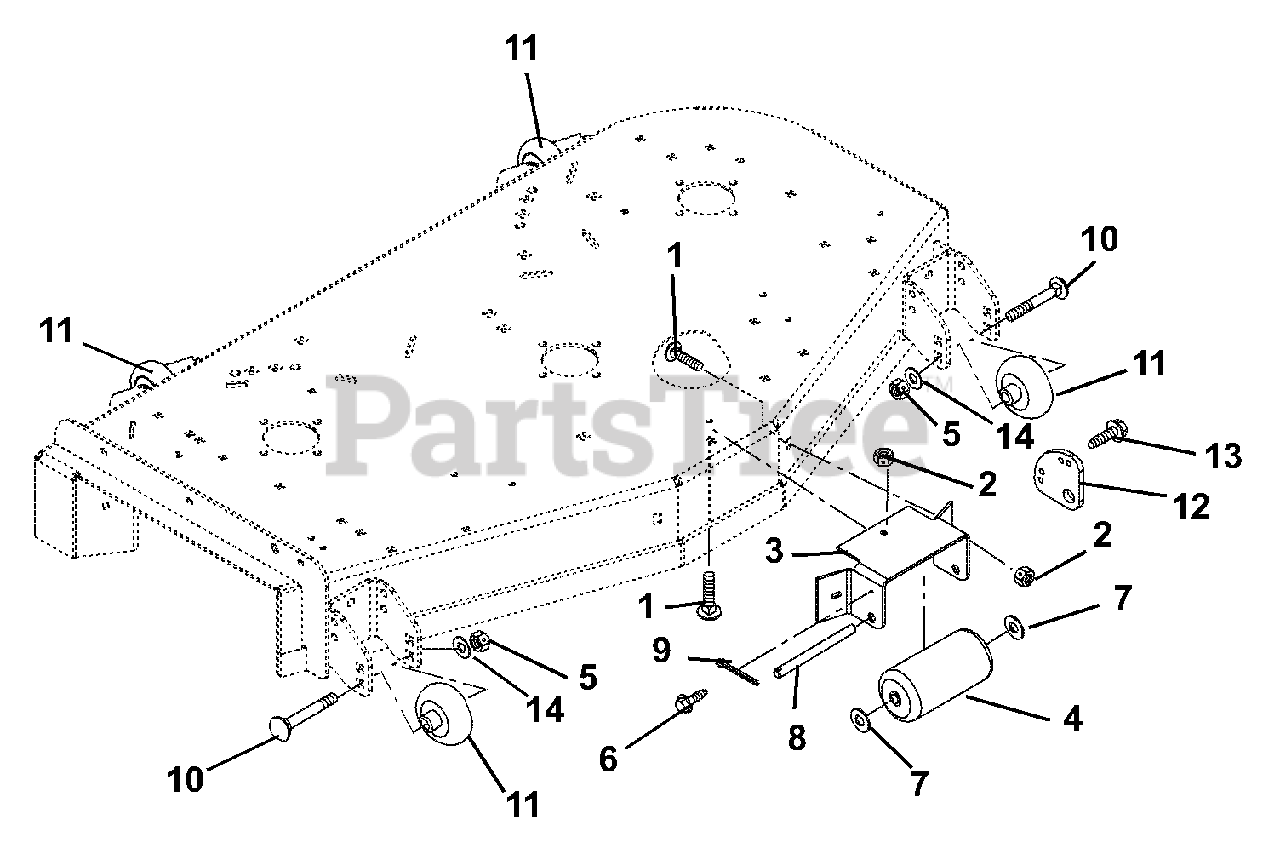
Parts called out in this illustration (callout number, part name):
1	@BLT-RDHDSQNK .38-16X1.00 G5YZ
2	@NUT-LK-TOP-FLG .38-16 YWZC
3	BRACKET - ANTI-SCALP ROLLER
5	@NUT-LK-NYL .50-13 YWZC
6	SCR-TAP .25-20X.75 HWH TR YWZ
7	@WSHR-FL-STL.656X1.31X.095 YWZ
8	PIN, 9.41 X .625
9	@PIN-CTR .25X2.00 YWZC
10	BLT-RDHDSQNK .50-13X5.00 GR5YZ
11	WHEEL, 3X5
12	ANTI-SCALP WASHER - RED
13	SCR-TAP.250-20X.62 HWH BLK ZC
14	@WSHR-FL-STL.531X1.06X.095YWZC
